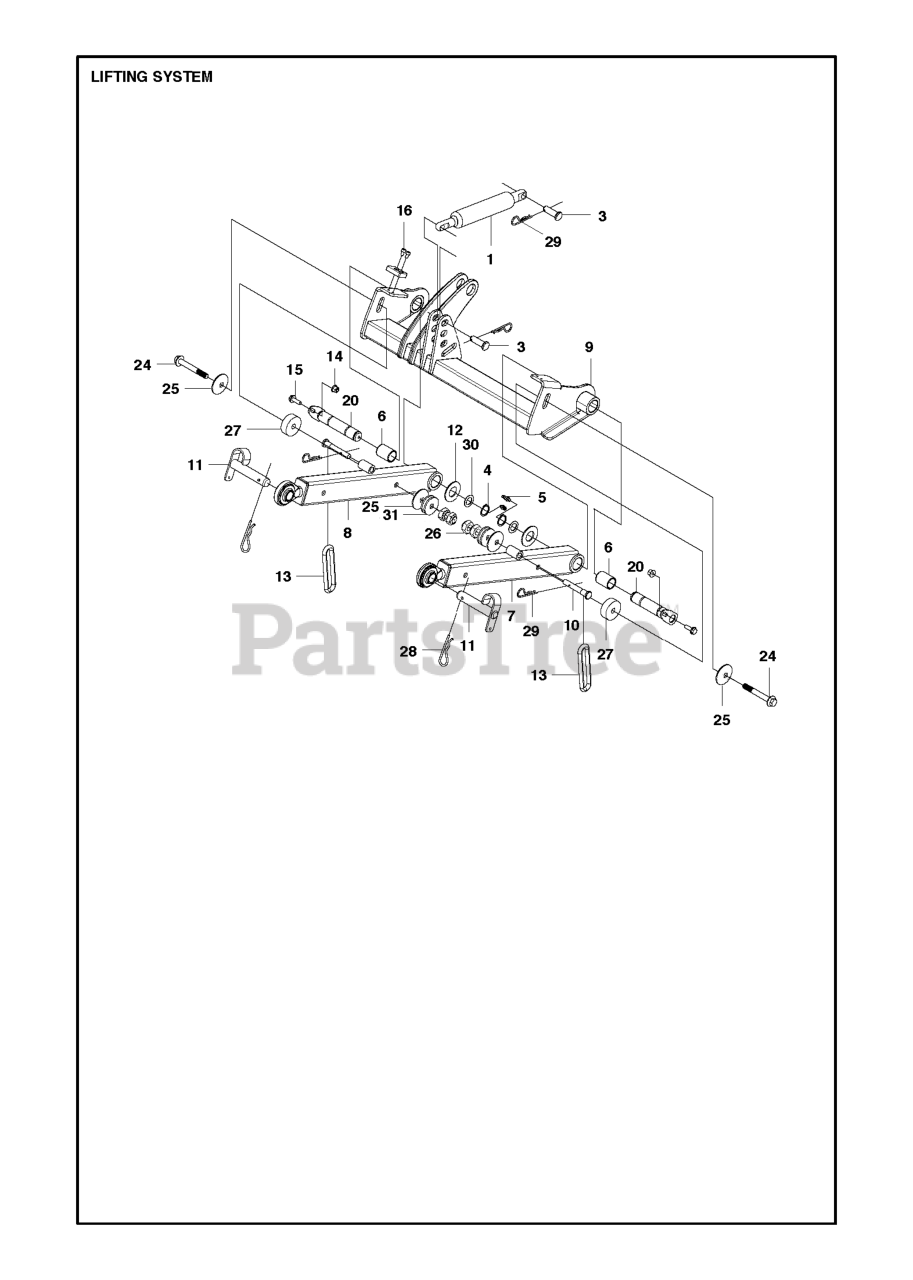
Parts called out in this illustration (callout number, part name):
3	CLEVIS PIN
11	Cotter Pins
13	LINK
14	NUT FLANGE
15	BOLT
16	SCREW MC6S 6X10
26	NUT HEXAGON THIN ISO 4035 M12
